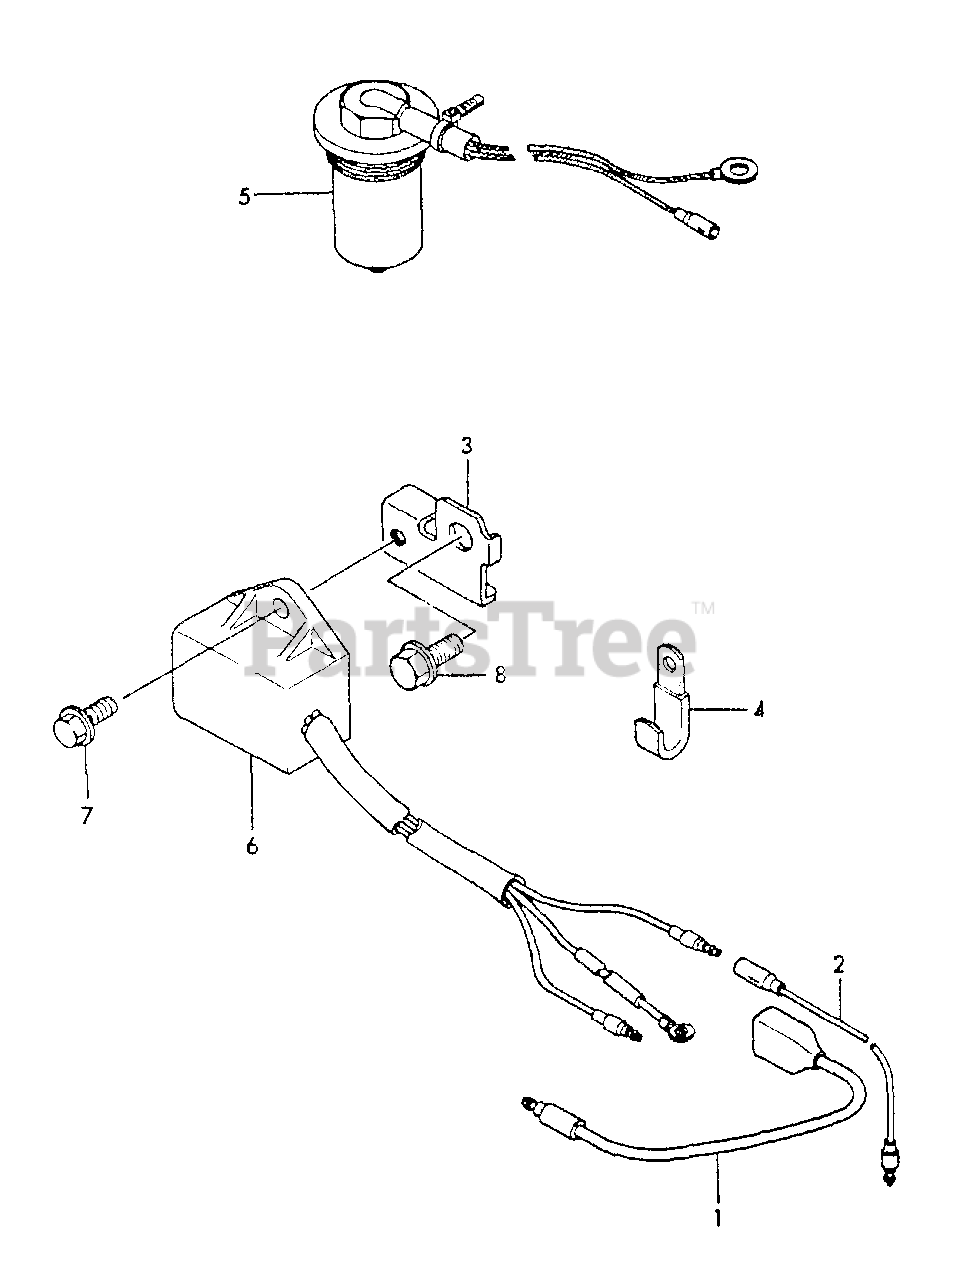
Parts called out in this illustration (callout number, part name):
1	WIRE
2	WIRE
3	STAY, SENSOR UNIT
4	CLAMP
5	SENSOR, OIL
6	SENSOR, OIL LEVEL
7	BOLT - 6X12 -- PLATED
8	BOLT - 8X14 -- PLATED
